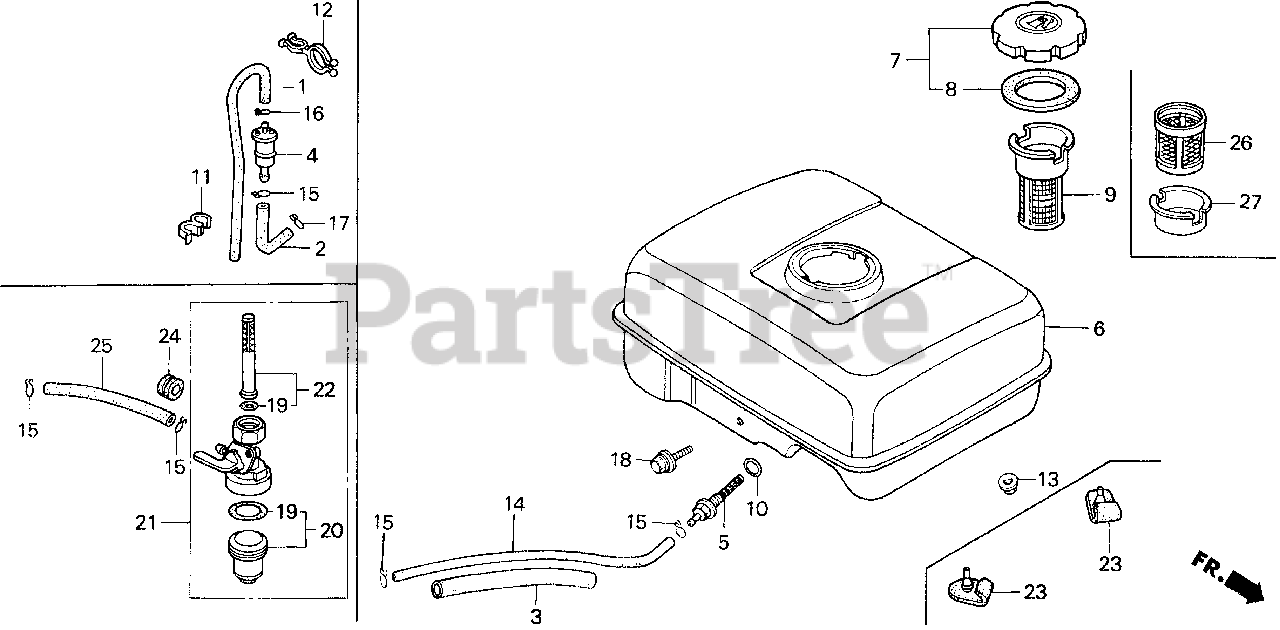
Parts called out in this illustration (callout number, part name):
3	RUBBER, SUPPORTER (107MM)
5	JOINT, FUEL TANK
6	TANK, FUEL *NH31* (MCKINLEY WHITE)
7	CAP, FUEL FILLER
8	GASKET, FUEL FILLER CAP
10	O-RING (13.5X1.5) (ARAI)
13	NUT, FLANGE (6MM)
14	BULK HOSE, FUEL (4.5X3000) (4.5X140)
15	CLIP, TUBE (B8)
18	BOLT, FLANGE (6X29)
18	BOLT, FLANGE (6X25)
